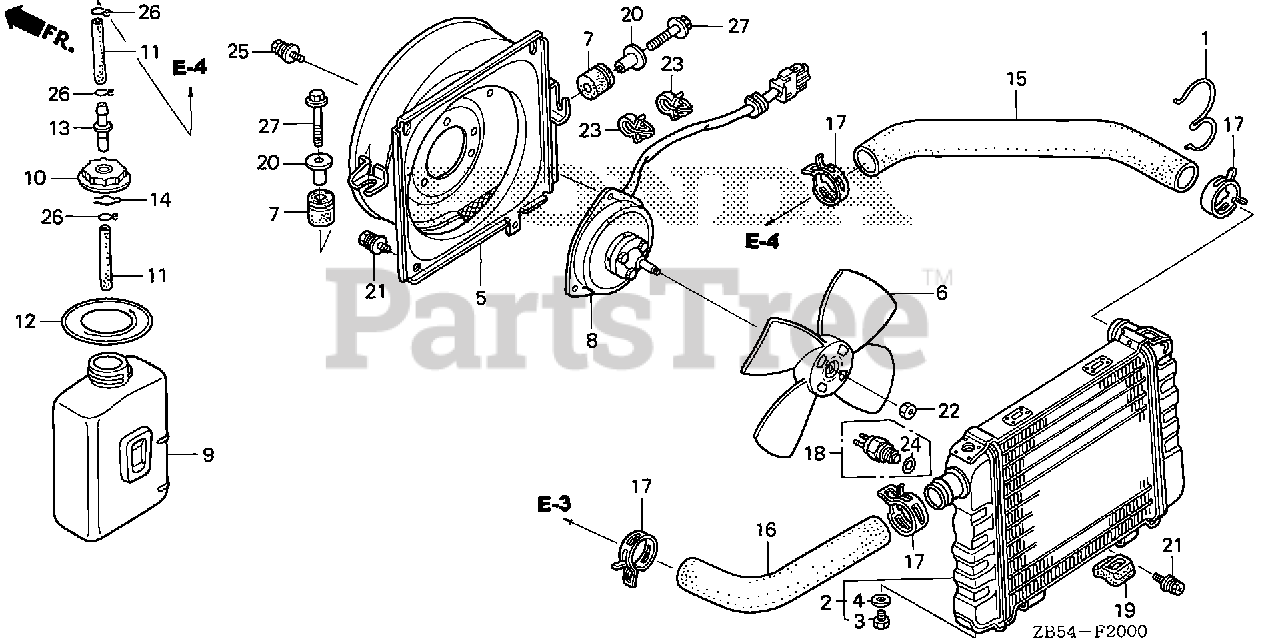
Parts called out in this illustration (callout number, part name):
1	CLAMP, IN. TUBE
3	PETCOCK, DRAIN
4	GASKET, DRAIN
6	FAN, COOLING
7	RUBBER, RADIATOR MOUNTING
8	MOTOR, COOLING FAN
9	TANK, RESERVE
10	CAP, RESERVOIR TANK
11	HOSE, RESERVE TANK
12	MARK, RESERVE TANK
13	JOINT, RESERVE TANK
14	CLIP, RESERVE TANK JOINT
15	HOSE, WATER (UPPER)
16	HOSE, WATER (LOWER)
17	CLIP, WATER HOSE
18	SWITCH ASSY., THERMOSTAT
19	CUSHION A, RADIATOR MOUNTING
20	COLLAR, RR. FENDER
21	BOLT-WASHER (6X10) (DENSO)
21	BOLT-WASHER (6X10)
22	NUT, HEX. (5MM) (DENSO)
23	CLIP B, CABLE (9MM BLACK)
24	O-RING (13.5X1.4)
25	SCREW-WASHER (5X10)
26	CLIP, TUBE (C11)
27	BOLT, FLANGE (6X30)
